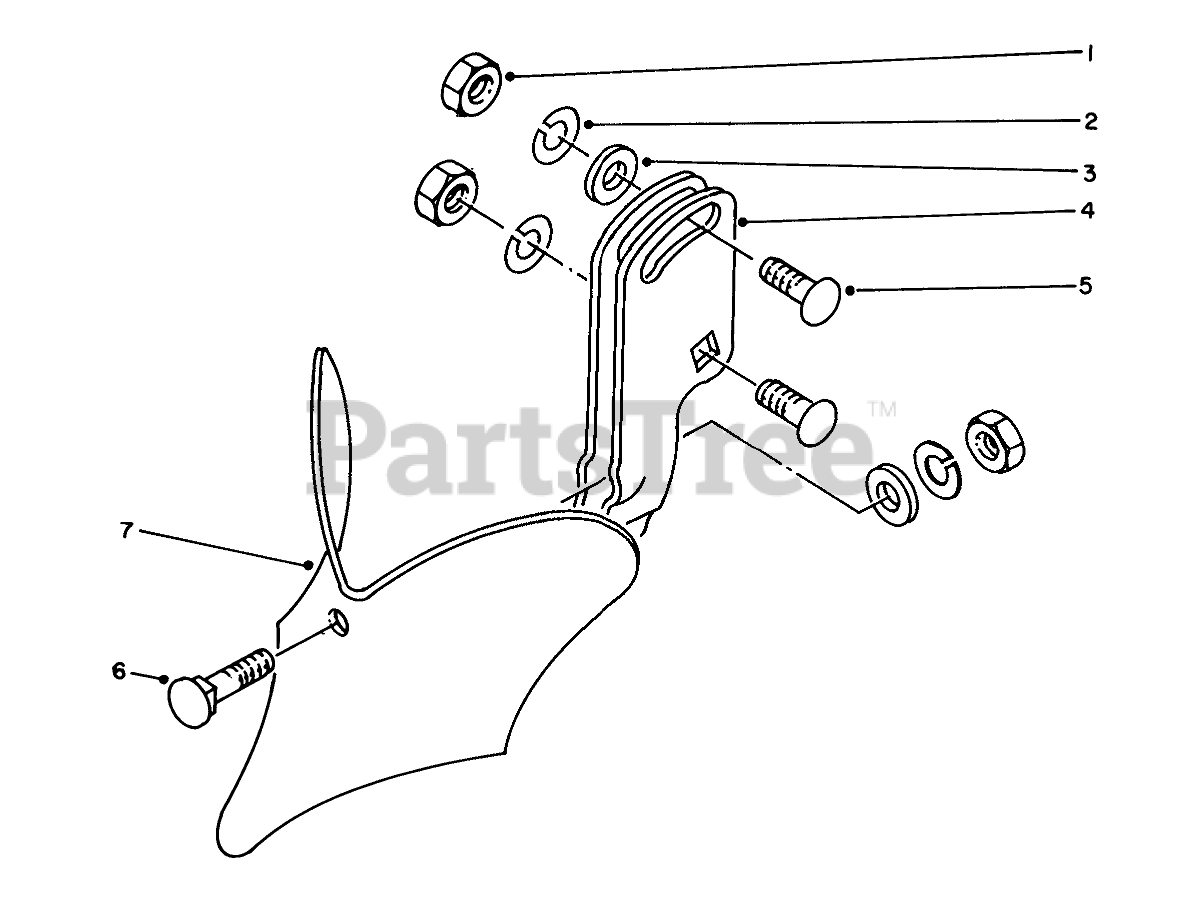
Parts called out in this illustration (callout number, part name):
1	NUT-HEX
2	WASHER-LOCK
3	WASHER-FLAT
4	Holder
5	BOLT-CARR
6	Plow Bolt
7	Shovel
